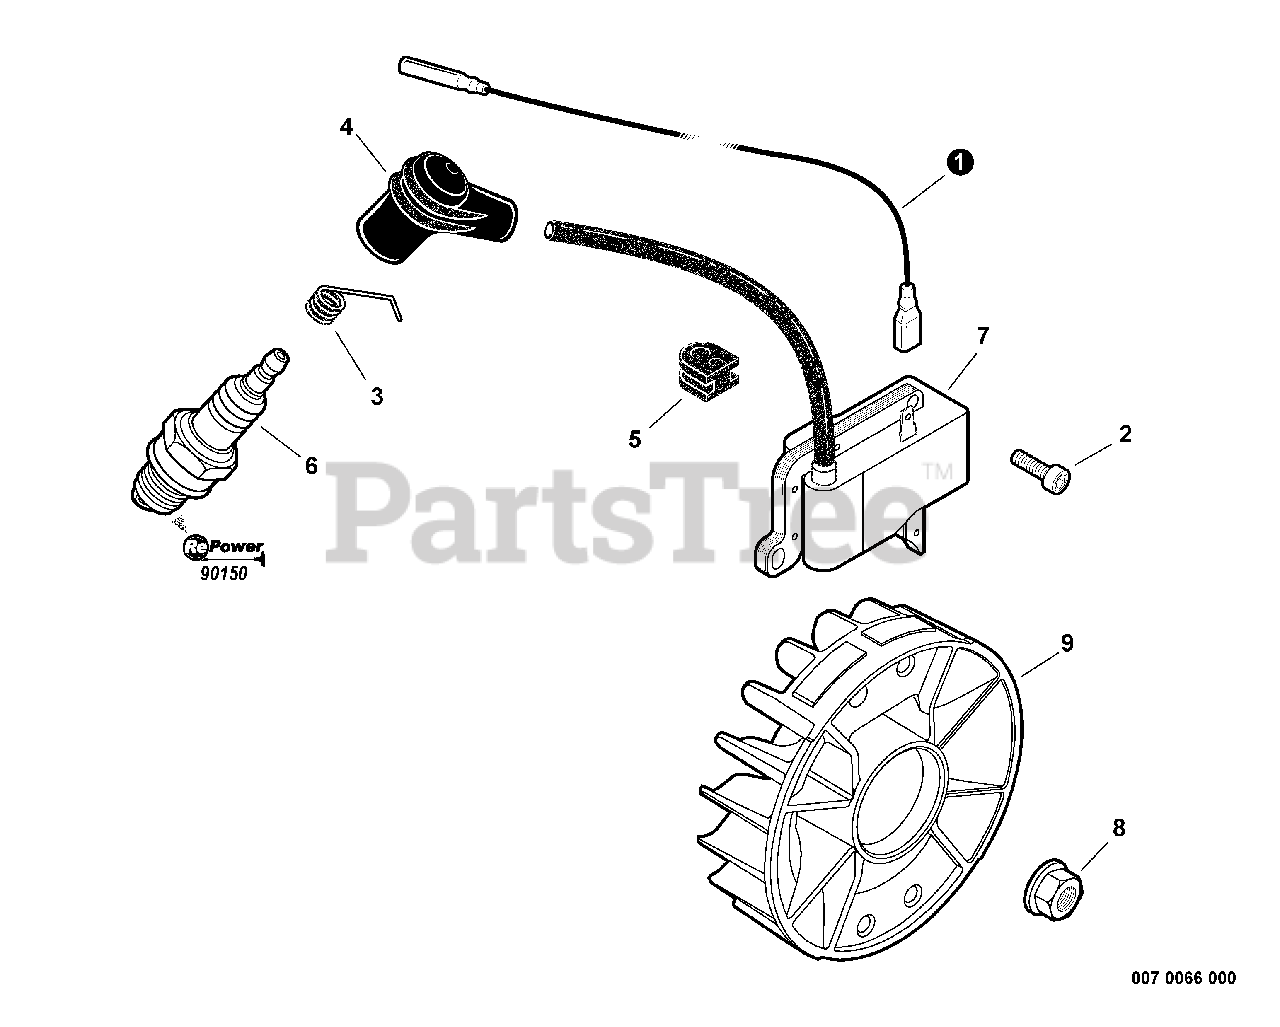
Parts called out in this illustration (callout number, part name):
1	LEAD L= 470
2	BOLT, TORX 5×20
3	TERMINAL, SPARK PLUG
4	CAP, SPARK PLUG
6	SPARK PLUG - BPM6Y
6	SPARK PLUG - BPMR6Y
7	COIL, IGNITION
8	NUT, FLANGE 10×1.25
9	FLYWHEEL
10	TUNE-UP KIT - REPOWER
